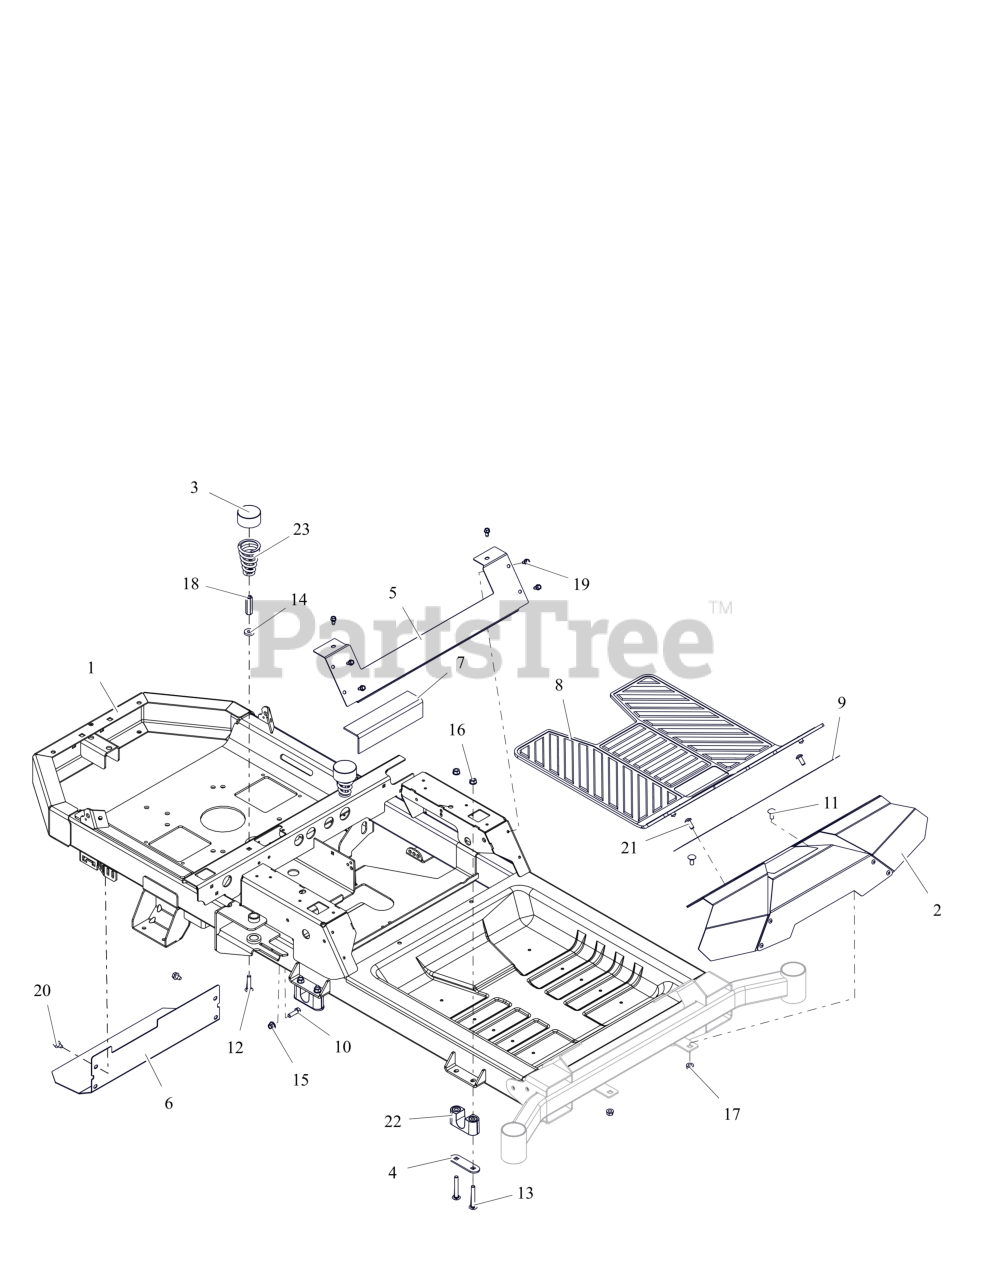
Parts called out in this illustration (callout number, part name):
1	WLDMT, FRAME IKON XD/ZTX & XL (ORANGE)
2	KIT, IKON FOOTREST W/ DECAL
3	HUB CAP
4	PLATE, BEARING SUPPORT
5	PLATE, SEAT KICK
6	HEAT, SHIELD
7	PAD, RUBBER-TANK
8	FLOOR MAT
9	GRIP TAPE, FOOT PLATE
10	BLT,HEX .31-18X1.00 G5 ZCC
11	BLT,RHSN .31-18X.75 G5 ZCC
12	BLT,RHSN .31-18X1.50 G5 ZCC
13	BLT, RHSSN.31-18X2.25 G5 ZCC
14	WSHR, FLT .328X.870X.179 ZCC
15	NUT,LK-NYL-FLG .31-18 G5ZC120
16	NUT,LK-CTR-FLG .31-18 GF ZCC
17	NUT-LK-TOP-FLG .312-18 GF ZCC
18	NUT, COUPLING .31-18X1.75 ZCC
19	SCR-TAP .25-20X.50 HWH ZCC
20	SCR,TAP .312-18X.50 HWH TR ZCC
21	SCR-RDHDSKTAP .31-18X.75 ZCC
22	BSHG, DECK LIFT PIVOT
23	SPRING, SEAT
